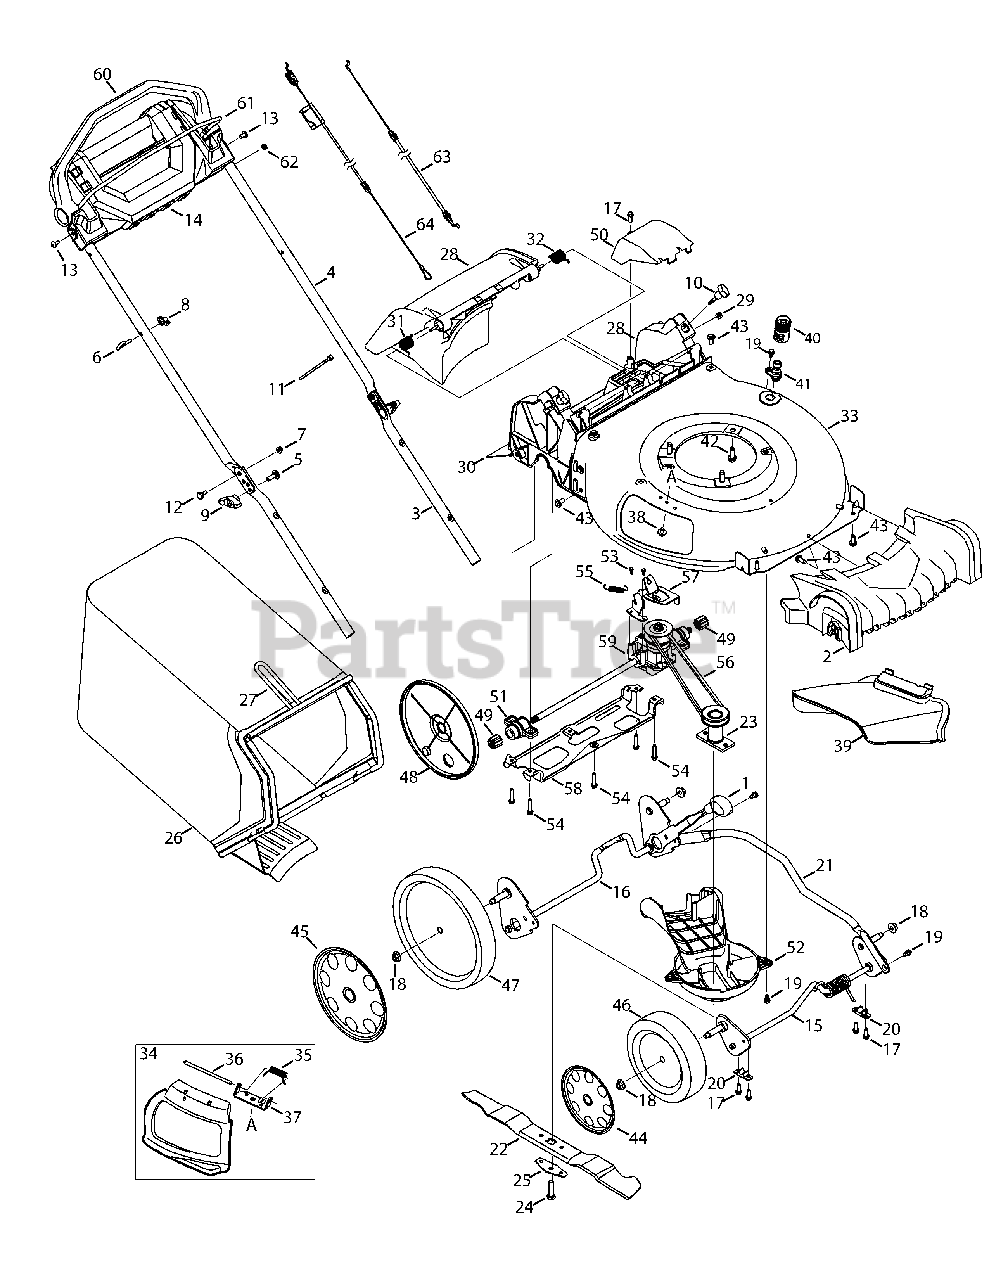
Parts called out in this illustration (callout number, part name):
1	Adjustment Lever Knob
2	Front Cover
3	Lower Handle
4	Upper Handle
5	Carriage Screw, 5/16-18
6	Rope Guide
7	Nut, Flange Lock, 1/4-20
11	Cable Tie
12	Sldr. Screw, .375 x .126 x 1/4-20
13	Screw, 1/4-14 x .625
14	Handle Console
15	Front Axle Assembly
16	Rear Axle Assembly
17	Screw, 1/4-15 x .750
18	Flange Lock Nut, 3/8-16
19	Scr., Shldr., 1/4-20 x .50
20	Bushing, Lock, .505 Dia. X .62
22	Mulching Blade
23	Blade Adapter
24	Screw, 3/8-24 x 1.50
25	Blade Bell Support
28	Rear Discharge Door Assembly
29	Nut, Sq., 1/4-20
30	Trailing Shield
31	Torsion Spring - RH
32	Torsion Spring - LH
34	Mulch Plug (Incl. 35-37)
35	Torsion Spring
37	Chute Deflector Bracket
38	Screw, 1/4-20 x .500
39	Side Discharge Chute
40	Water Nozzle Adapter
41	Water Nozzle
42	Screw, 3/8-16 x 1.00
43	Screw, 5/16-14 x .750
44	Hubcap, 8"
45	Hubcap, 11"
46	Front Wheel
47	Rear Wheel
48	Wheel Dust Cover
49	Spur Gear, 9T
50	Transmission Cover
51	Bearing Assembly
52	Engine Baffle
53	Screw, Hex Washer, .159 x .43
54	Screw, 1/4-15 x 1.25
55	Exten. Spring, 2.405
57	Transmission Bracket
58	Rear Support Bracket
59	Transmission Assembly
60	Drive Handle
61	Blade Control
62	Shoulder Spacer, .18 x .315 x .09
63	Control Cable
64	Drive Cable
